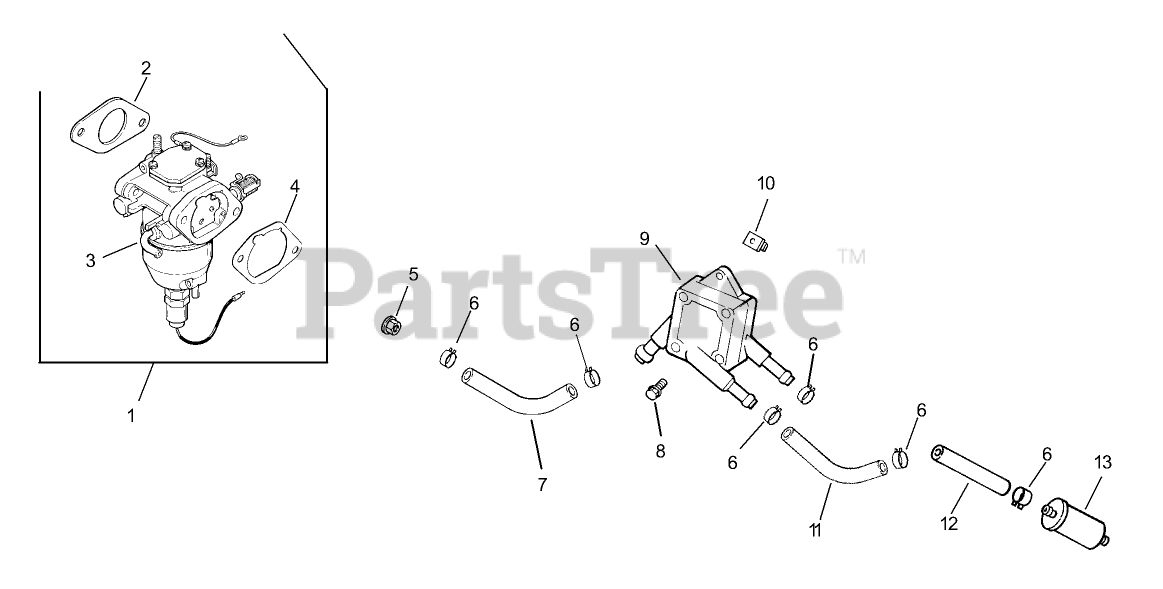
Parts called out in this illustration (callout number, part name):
1	Kit, carburetor w/gaskets (Includes 2-4)
2	Gasket-carburetor
3	Carburetor assembly (For information only not available separately)(Service with kits 24 234 02-S, 24 757 18-S, 24 757 19-S, 24 757 20-S, 24 757 21-S and 24 757 22-S)
4	GASKET-BASE, AIR CLEANER
5	NUT-FLANGE (M6X1.0)
6	CLAMP-HOSE, SPRING (1/2)
7	Line, fuel 6-1/4
8	SCREW-TAP (M6X1.7X18)
9	PUMP-FUEL
10	Nut-Plastic
11	Line, fuel 10-1/2
12	Line, fuel 12"
13	Filter-Fuel
